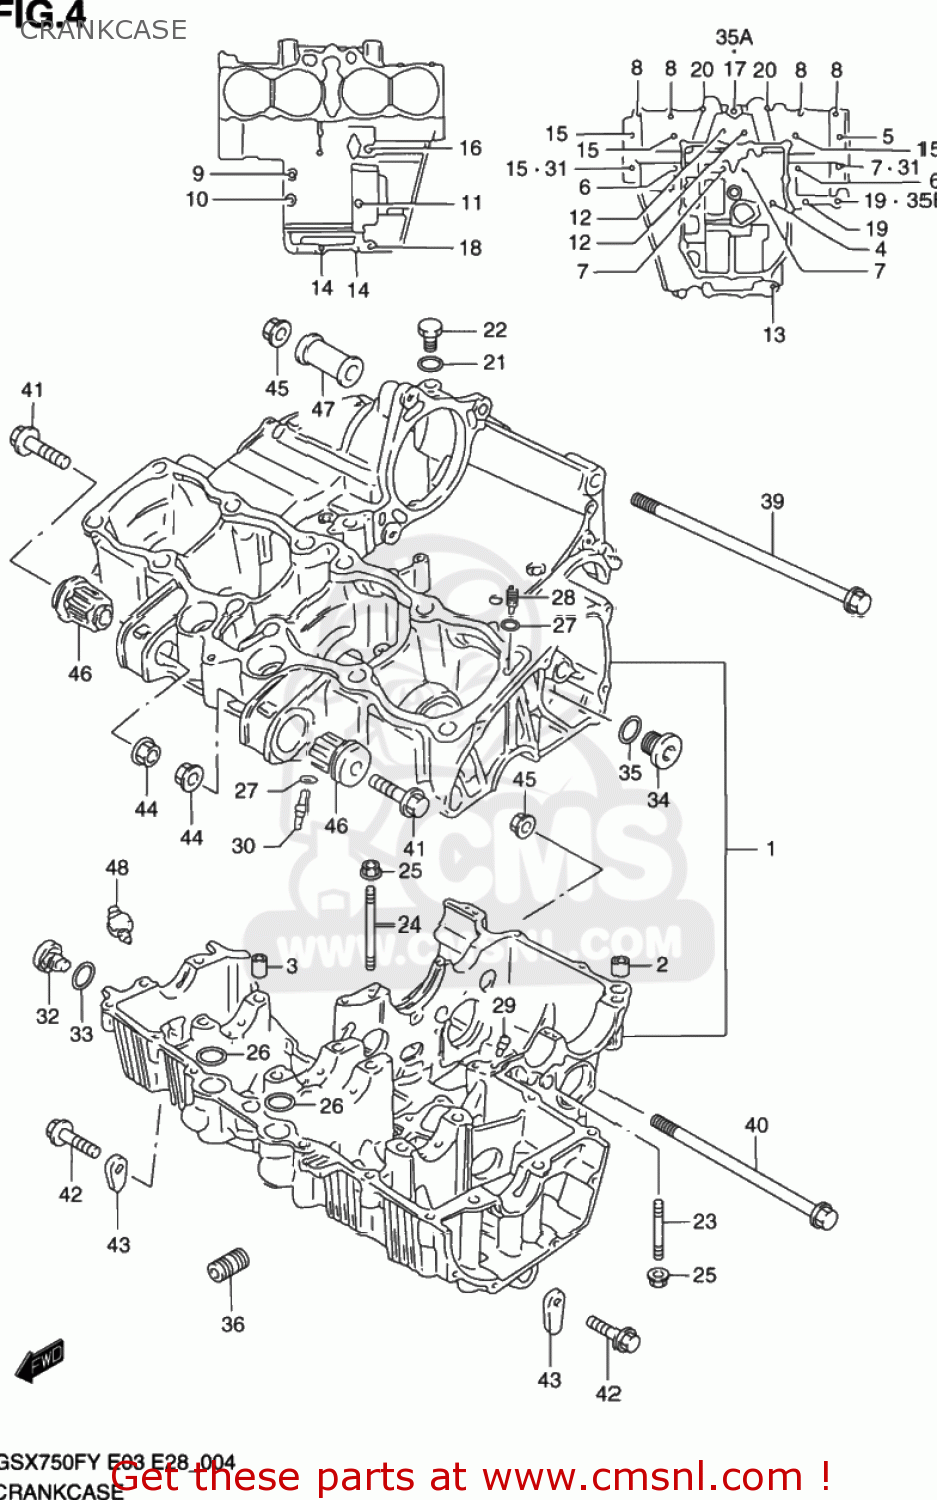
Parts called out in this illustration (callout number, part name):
1	CRANKCASE SET
2	PIN(10.4X13X22)
3	PIN(8.4X11X20)
4	BOLT(6X105)
5	BOLT(8X105)
6	BOLT(8X125)
7	BOLT(8X115)
8	BOLT
9	BOLT
10	BOLT,CL.COVER
11	BOLT
12	BOLT
13	BOLT
14	BOLT
15	BOLT(8X95)
16	BOLT
17	BOLT
18	BOLT
19	BOLT, HYDRAULIC UNIT NO.2
20	BOLT
21	GASKET(12.1X16.2X3.7) (NAS)
22	PLUG(12X9)
23	STUD BOLT
24	STUD BOLT
25	NUT
26	O RING(D:2.5,ID:21)
27	O RING(D:1.2,ID:4)
28	JET,AIR
29	JET
30	JET(13)
31	GASKET(8.5X17X2.3) (NAS)
32	PLUG
33	O RING(D:2.4,ID:16.8)
34	PLUG
35	GASKET(13.8X18.8X4.8) (NAS)
35A	GASKET(5.8X13X1.2) (NAS)
35B	GASKET(5.8X13X1.2) (NAS)
36	UNION,OIL STAND
37	PLATE,CRANK THRUST
38	PLATE,CRANK THRUST
39	BOLT(10X175)
40	BOLT(10X130)
41	BOLT
42	BOLT(10X50)
43	NUT
44	NUT
45	NUT
46	BUSH,ENGINE MOUNTING
47	SPACER,ENGINE MOUNT(L27)
48	SWITCH ASSY,OIL PRESSURE
